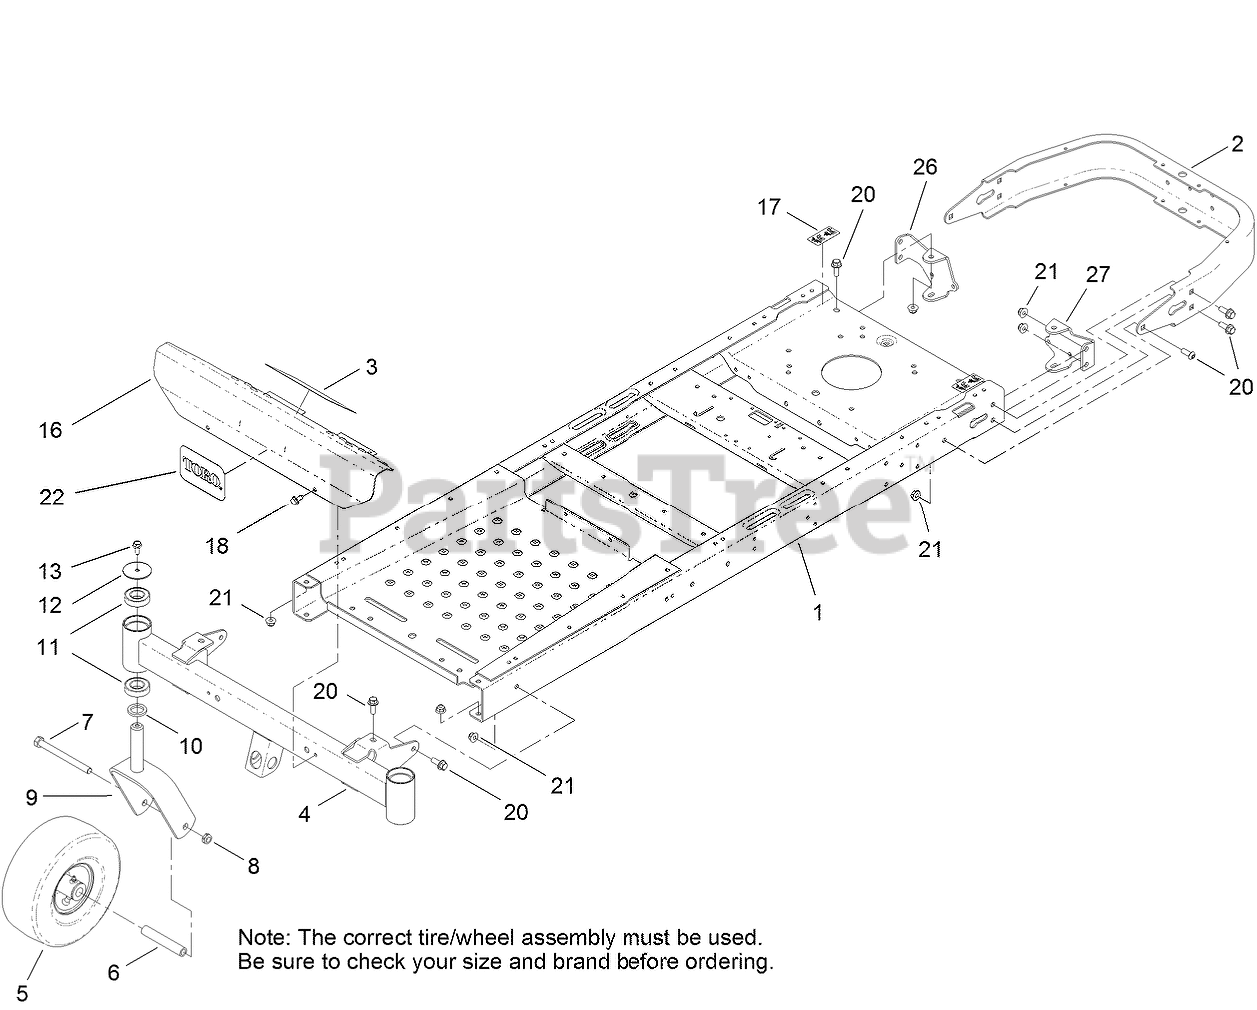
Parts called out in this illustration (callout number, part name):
2	BUMPER-REAR
3	DECAL-DANGER
4	AXLE-FRONT
5	CASTER WHEEL ASM (CST)
5	CASTER WHEEL ASM (Kenda)
6	BUSHING-SPANNER
7	SCREW-HH
8	NUT-LOCK, NI
9	CASTER FORK ASM
10	WASHER-THRUST
11	BEARING-BALL
12	WASHER
13	SCREW-HHF
16	FOOTREST
17	DECAL-BYPASS
18	SCREW-HWHTF
20	SCREW-HHF
20	SCREW-HSBH
21	NUT-HF, NI
26	MOUNT-HYDRO, REAR (RH)
27	MOUNT-HYDRO, REAR (LH)
